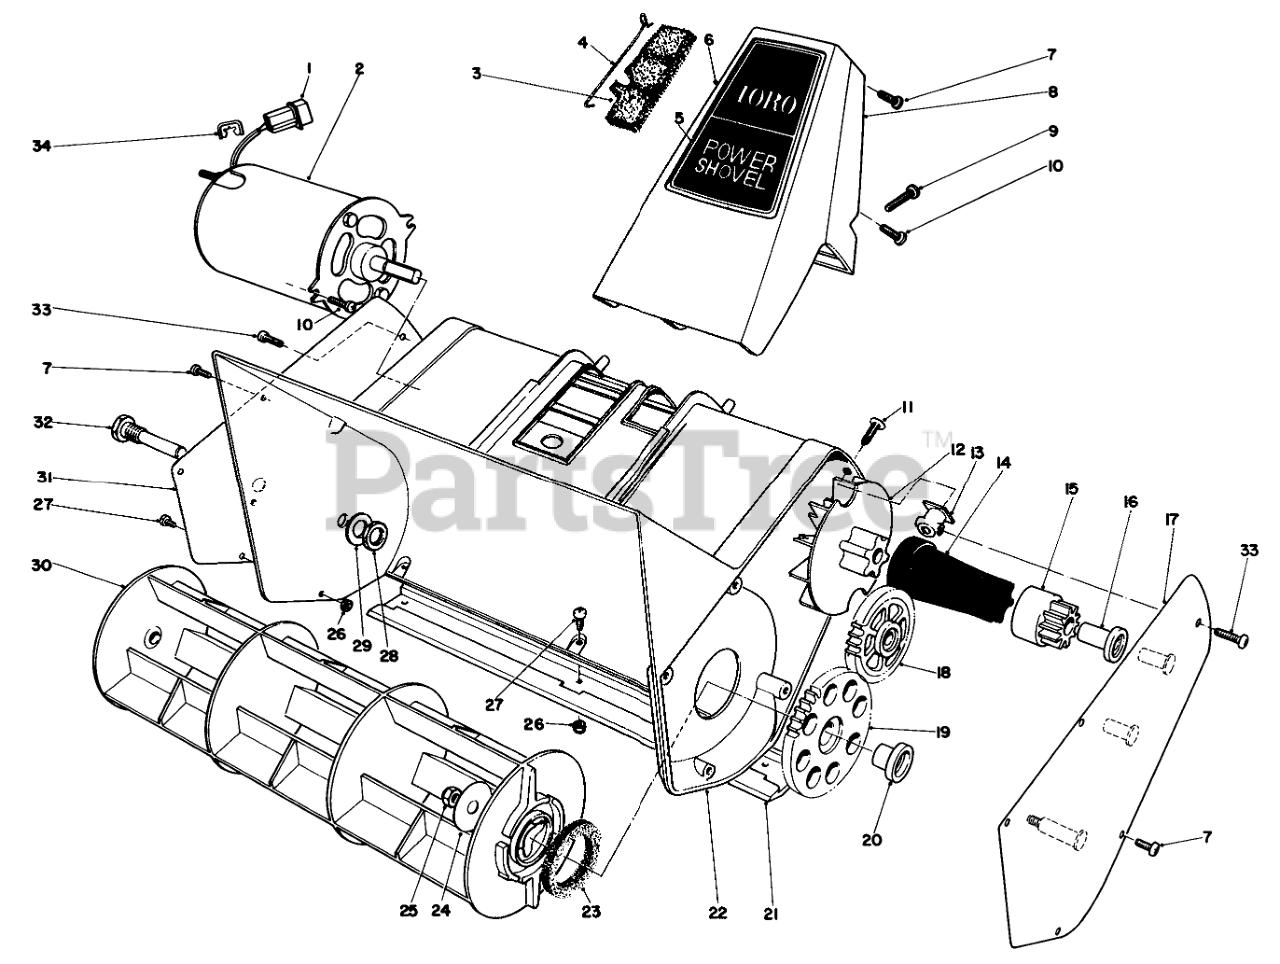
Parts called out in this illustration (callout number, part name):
1	Pin Housing
2	ELEC MOTOR
3	FOAM FILTER
4	RETAINER - FILTER
5	HANDLE SUPT DECAL
6	Handle Support-Front
7	SCREW-PPH
8	Handle Support-Back
9	SCREW-PPH
10	SCREW-PPH
11	XMAS TREE FASTENER
12	FAN, POWER SHOVEL
13	MTG BLOCK
14	DRIVE COUPLING
15	Drive Gear (Incl. Ref. #16)
16	BUSHING, DRIVE GEAR
17	Gear Carrier
18	Idler Gear
19	Rotor Gear Assembly (Incl. Ref. #20)
20	BUSHING, ROTOR GEAR
21	Scraper
22	Housing
23	FELT WASHER
24	ROTOR WASHER
25	NUT-LOCK, NI
26	NUT-LOCK
27	SCREW-PPH
28	3/8 24 JAM NUT
29	WASHER-FLAT
30	ROTOR
31	RT. SIDE COVER (RAW)
32	ROTOR PIN
33	Screw
34	Strain Relief
